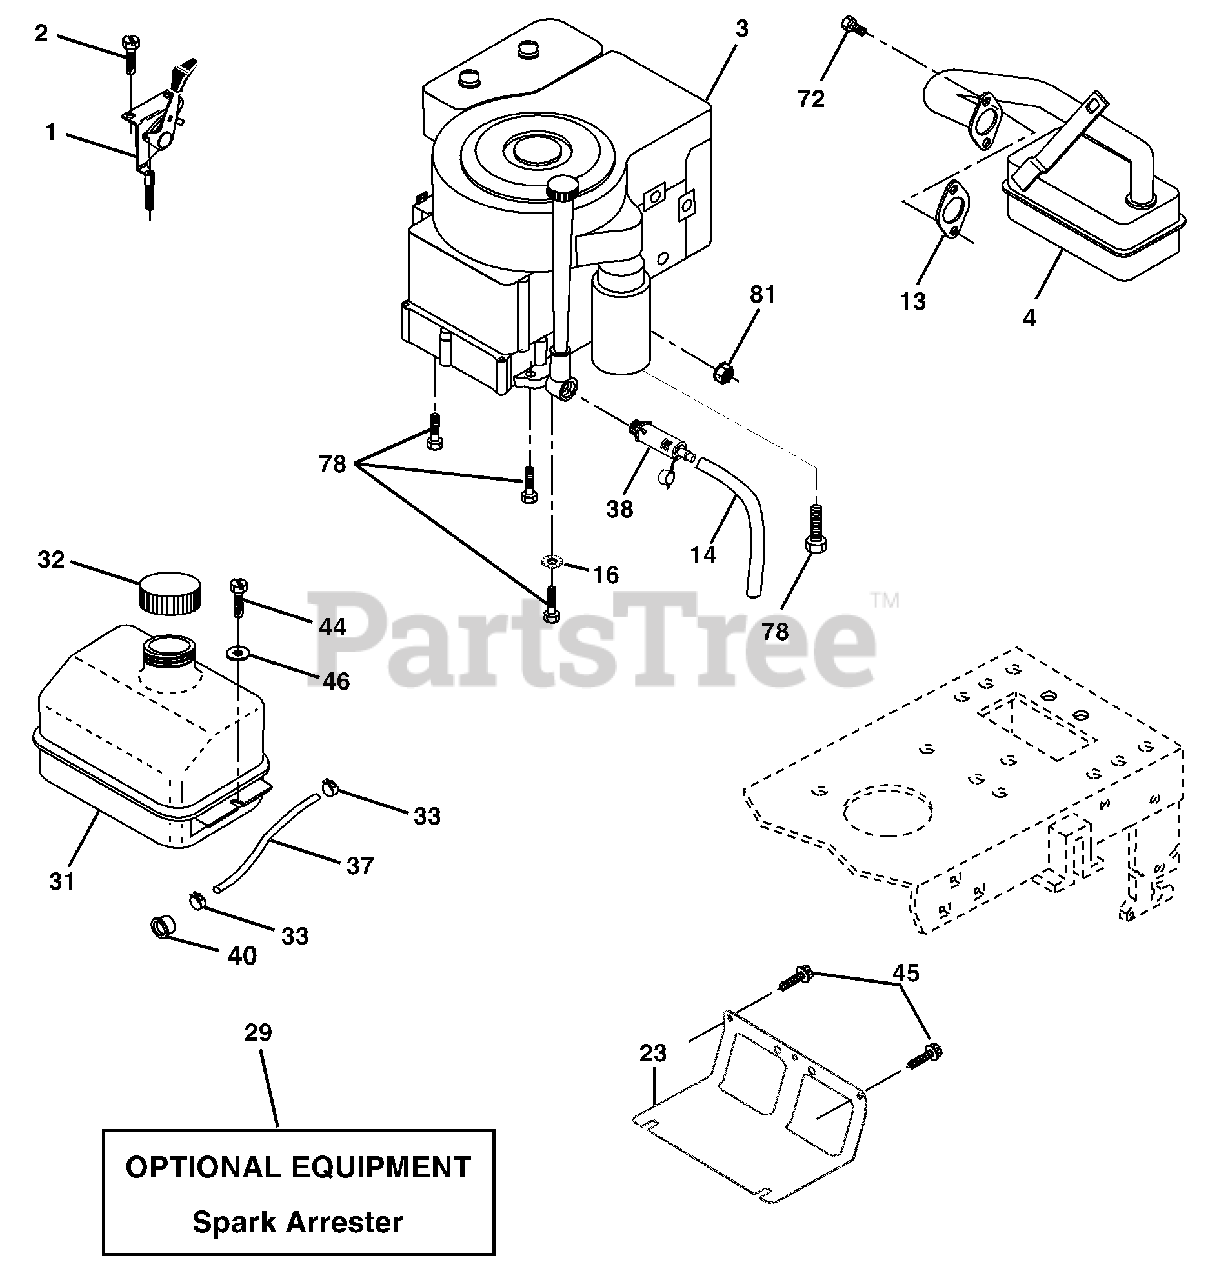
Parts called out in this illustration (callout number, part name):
1	Control Throt /Ch Flag
2	Screw Hex Thd Cut 1/4-20 x 1/2
4	Muffler Exhaust B&S Lt
13	Gasket 1 313 Id Tin Plated
14	Tube Drain Oil Easy
16	Washer Lock Ext Tooth 3/8
23	Shield Browning/Debris Guard
29	Arrestor Spark
31	Tank Fuel 1 25 Fr
32	Cap Asm Fuel W/sym Vented
33	Clamp Hose Blk
37	Line Fuel 20"
38	Plug Drain Oil Easy
40	Bushing Snap Nyl Blk Fuel Line
44	Screw Hexwsh Thdrol 1/4-20 x 3/4
45	Screw Hex Wsh Thdrol 3/8-16
46	Washer 9/32 x 7/8 x 16 ga
72	Screw Socket Head 5/16-18 x 1
78	Screw Thdrol 3/8-16 x 1-1/4
81	Nut Keps Hex 1/4-20 Unc
